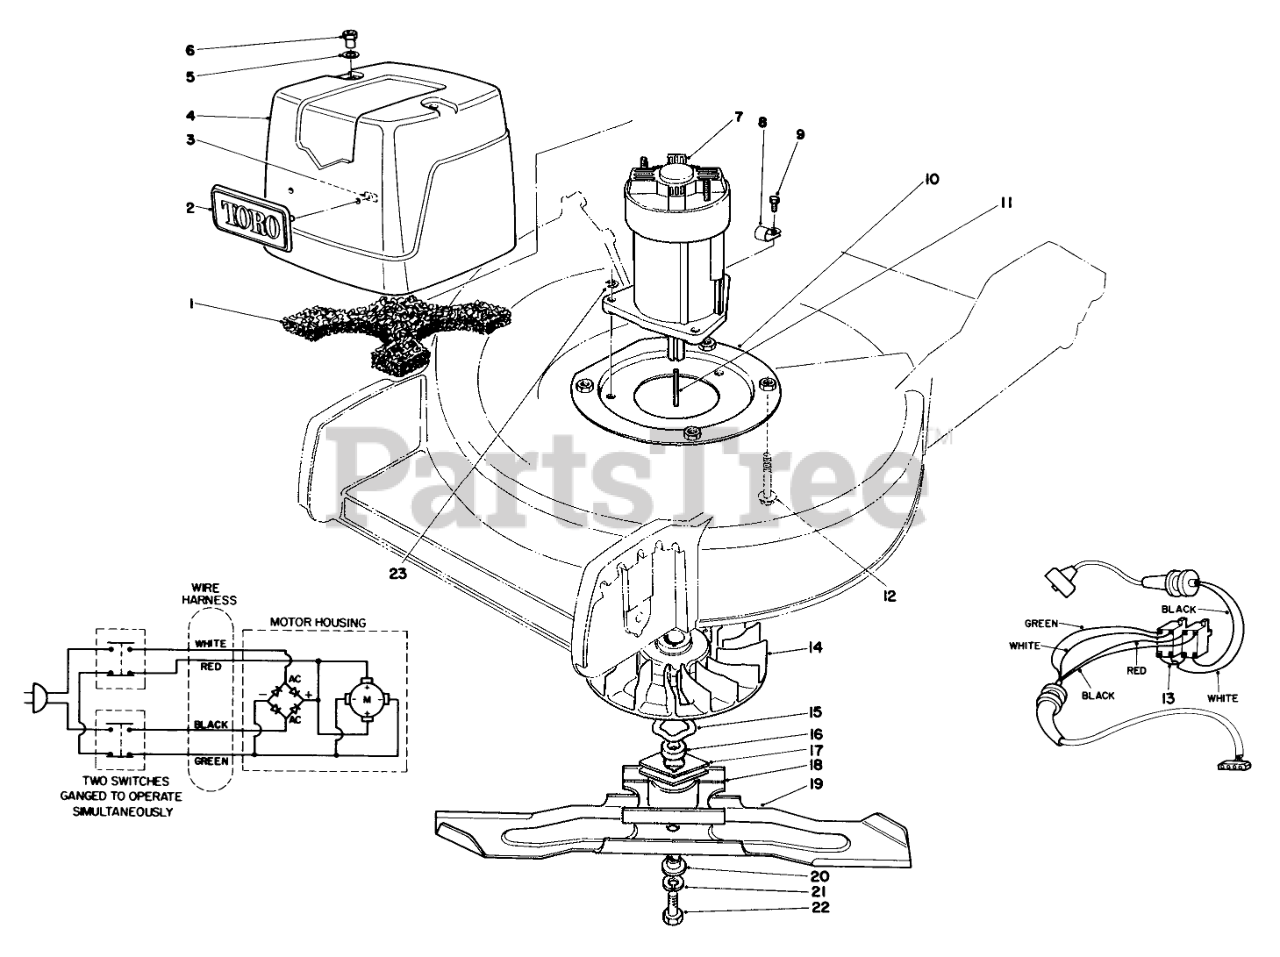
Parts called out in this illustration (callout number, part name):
1	FILTER F/W
2	TORO LOGO PLT
3	Receiver-Stud
4	Shroud-Motor
5	WASHER F/W
6	NUT F/W
7	Motor-Electric
8	CLIP-CLOSED, INSULATED
9	SCREW-HH
10	MOTOR MOUNT ASM WA
11	1/8 X 1/40 SQUARE KEY
12	SCREW-HHF
13	BRAKE WIRE
14	FAN F/W
15	WAVE WASHER
16	BLADE RETAINER SPACER
17	FAN DRIVER
18	BLADE RETAINER WA
19	Blade
20	BLADE SPACER
21	WASHER-LOCK/SP
22	SCREW-HH
23	WASHER-LOCK/EXT
